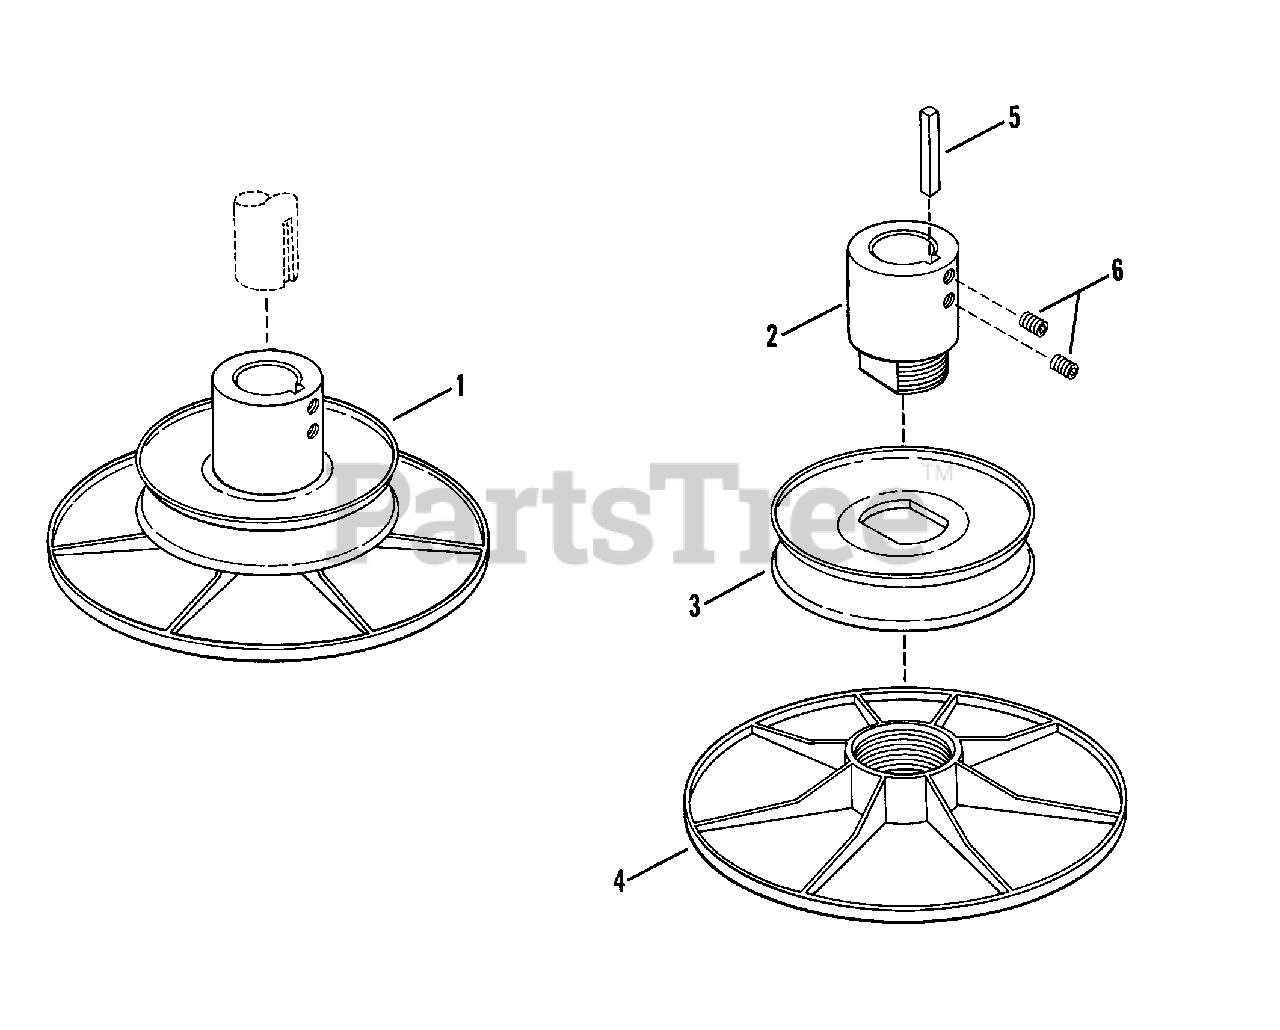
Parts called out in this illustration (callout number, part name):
1	ASSEMBLY, Drive Disc, 4" O.D.
2	HUB
3	PULLEY, 518" O.D.
4	DISC, Drive
5	KEY, 1/4x1/4x2"
6	SET-SCREW, 3/8-16x3/8"
